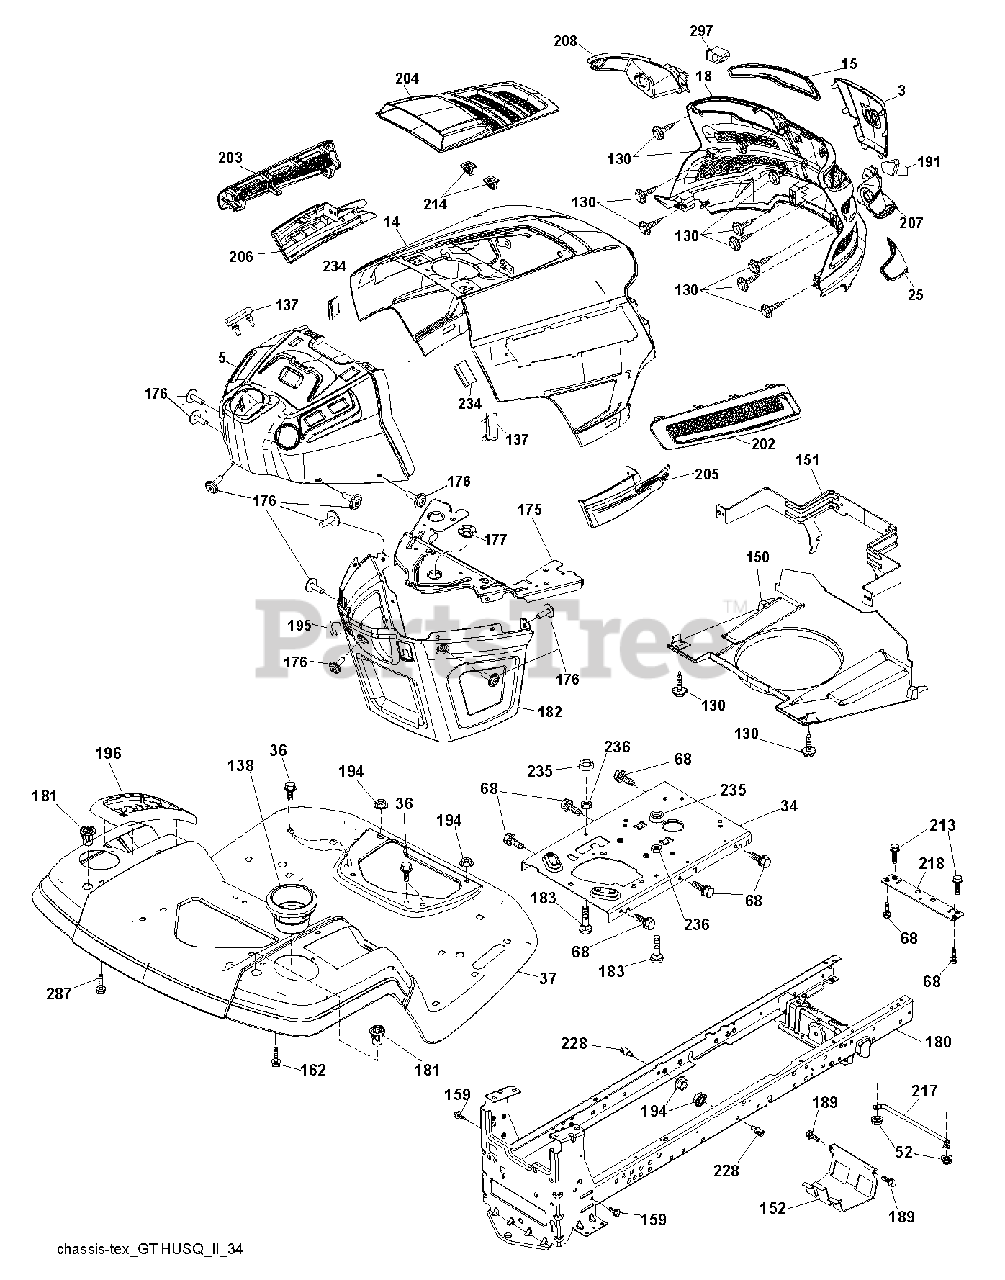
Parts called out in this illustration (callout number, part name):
3	APPLIQUE.SUBASM.GT.HUSQ.II
5	RP.DASH.UPP.GT2.SM.MC.CHOKE
14	HOOD.ASM.HUSQVARNA.GT.TEX.ORAN
15	LENS.HEADLIGHT.LH.GTII.2011
18	GRILLE.SUBASM.GT.HUSQ.II
25	LENS.HEADLIGHT.RH.GTII.2011
34	PLATE.ENGINE.WELDED.CHASSIS
36	SCREW 5/16"
37	FENDER.TLT.PDL.CNTRL.W/CPH.ORG
52	LOCKNUT
68	SCREW LT
130	SCREW.#10 X 0.750.BOS
137	BUMPER DASH
138	HOLDER.CUP.LT.GREY
150	AIR DUCT.GTV2(1.66"RING HEIGHT
151	BRACKET.PIVOT.HOOD.GT.HUSQ.II
152	SHIELD.BROWNING.W/TEX
159	SCREW, 3/8-16X3/4
162	SCREW.HI-LO.CONSOLE
175	PLATE.CROSSMEMBER.HUSQ
176	SCREW.#10-24X5/8.RN.QU
177	BUSHING, STEERING
180	CHASSIS
181	BUSHING.MNT.FEND.CRGO.
182	DASH.LOWER.COMMON.12V.ADAPTOR
183	BOLT.5/16-18X1-1/4 FULL THD
189	SCREW
191	INSERT.REFLECTIVE.RH.HUSQ.GTII
194	NUT LOCK HEX FLANGE 5/16-18
195	PLUG.HOLE.DASH.LOWER.12V.BLK
196	DECKLFT.CONSOL FULL ASSM GREY
202	VENT.SIDE.RH.GT.HUSQ.II.
203	VENT.SIDE.LH.GT.HUSQ.II.498
204	VENT.TOP.HUSQ.GT2
205	SIDE.TRIM.RH.GT.HUSQ.II
206	SIDE.TRIM.LH.GT.HUSQ.II.GRAY
207	BEZEL LIGHT.RH.GT.II.MYLAR
208	BEZEL LIGHT.LH.GT.II.MYLAR
213	BOLT
214	CLIP.RETAINER.TINNER.
217	ROD.PIVOT.HOOD
218	X-PIECE.HOOD.STOP.NON/
228	STUD.FASTNER.W/ANTI-ROTATE
234	BUMPER.HOOD.TEX.HUSQVARNA
235	SPACER FENDER
236	NUT.CENTERLOCK.5/16-
287	SCREW 1/4X20
297	INSERT.REFLECTIVE.LH.HUSQ.GTII
